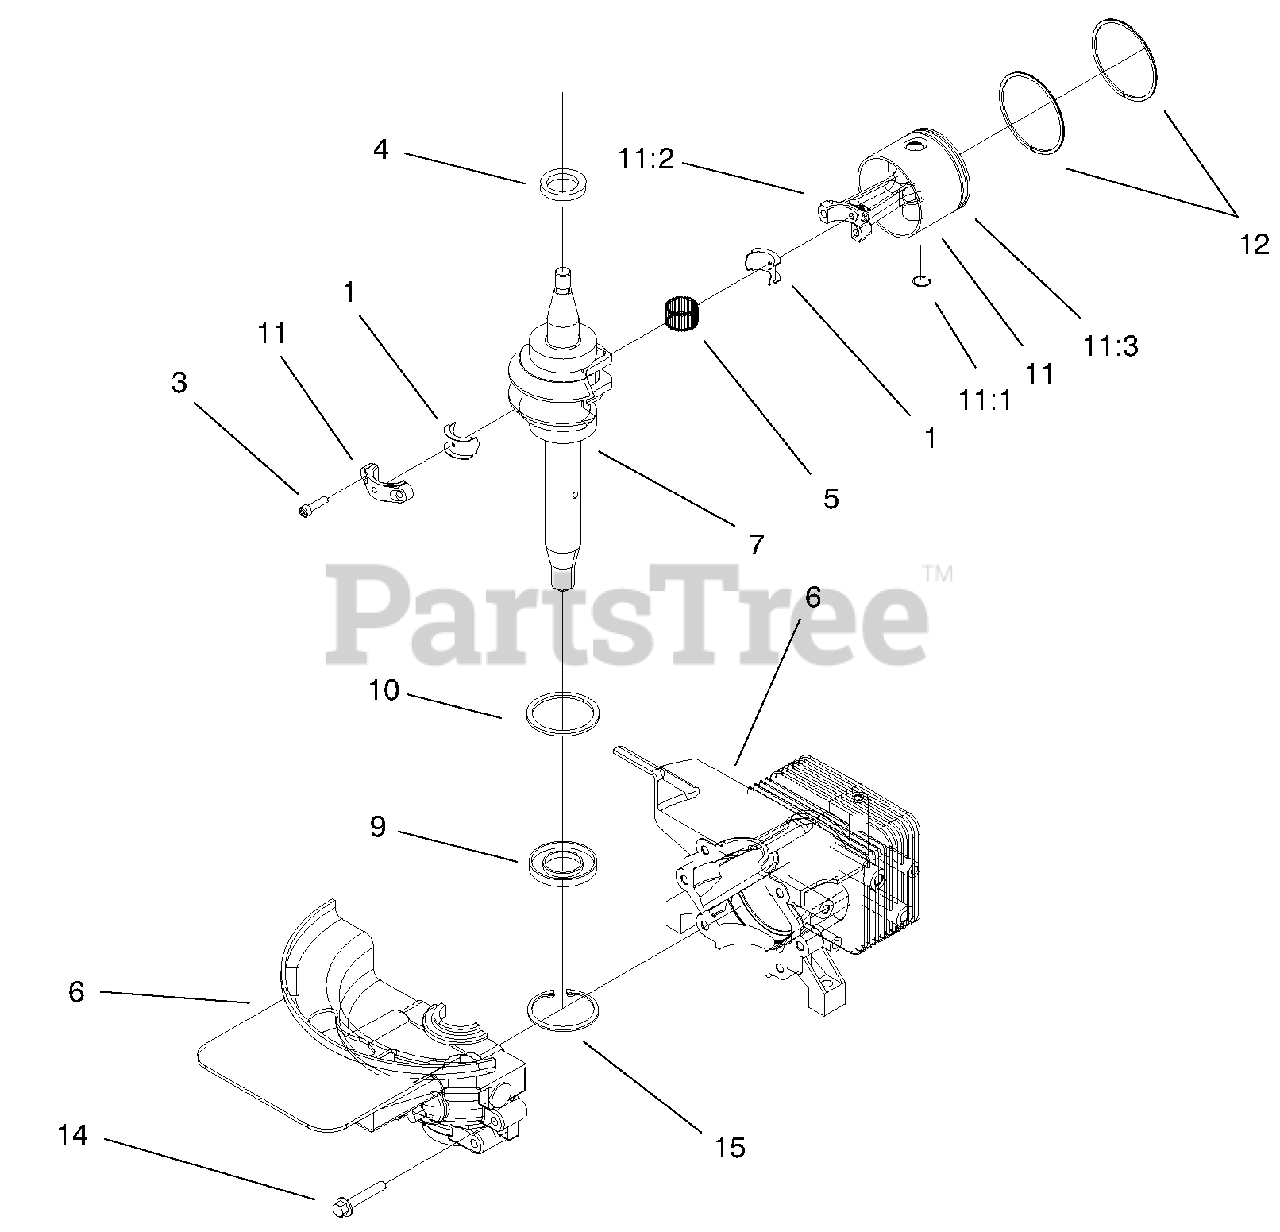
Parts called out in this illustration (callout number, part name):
1	Liner Ay
2	Sealant-50cc #2
2	Sealer-Loctite
3	Screw-Rod
4	Seal- Oil
5	Bearing-Needle
6	Cylinder And Crankcase ASM
7	Crankshaft And Bearing ASM For Service
9	Seal-Oil
10	Ring-Retaining
11	Piston&rod Ay
11:1	Ring-Retaining
11:2	Connecting Rod ASM
11:3	Piston ASM With Piston Rings
12	Ring Set-Service
15	Ring-Retaining
